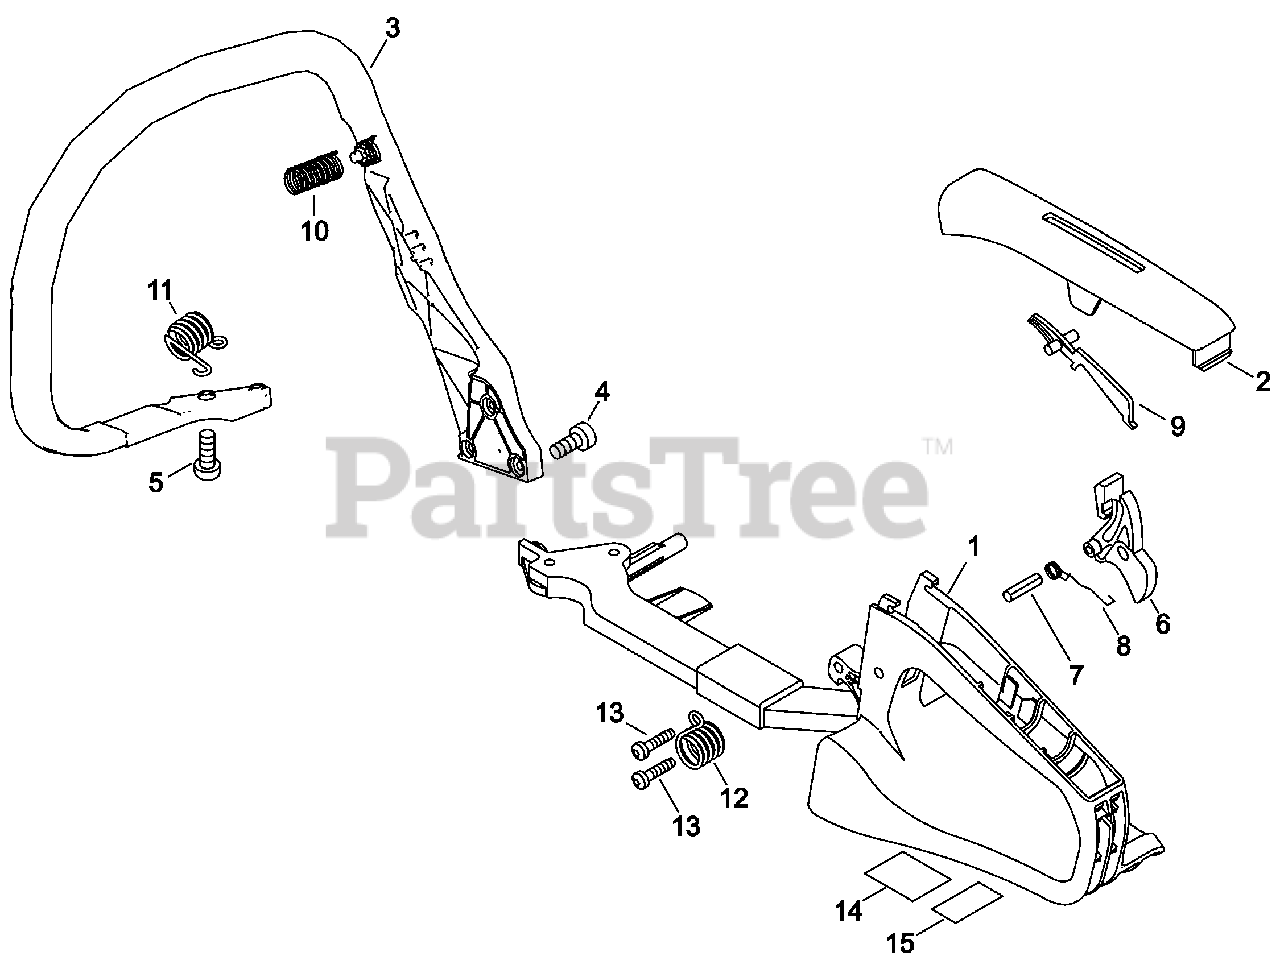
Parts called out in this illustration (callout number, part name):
1	HANDLE, REAR
2	COVER, HANDLE
3	HANDLE, FRONT
4	BOLT, TORX 5×20
5	BOLT, TORX 5×16
6	TRIGGER, THROTTLE
7	PIN, SPRING 4×25 SUS
8	SPRING, TORSION
9	LOCKOUT, THROTTLE
10	SPRING, COMPRESSION
11	SPRING, COMPRESSION
12	SPRING, COMPRESSION
13	BOLT, TORX 5×16
14	LABEL, CAUTION
15	LABEL, CAUTION
